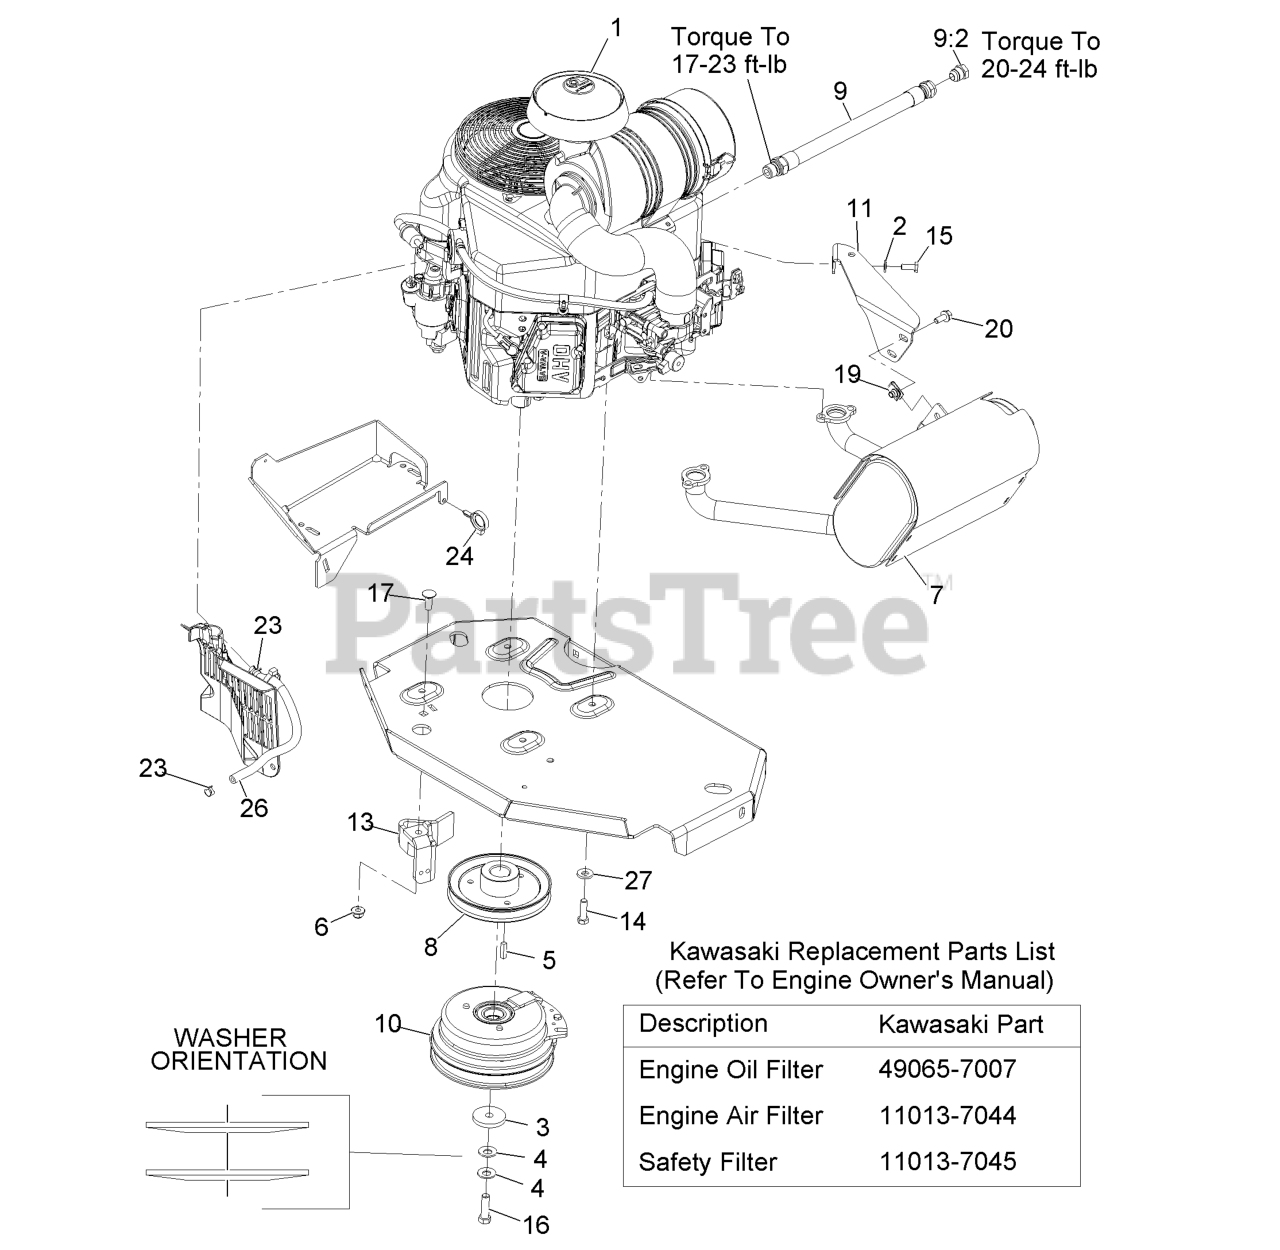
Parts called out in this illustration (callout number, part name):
2	WASHER-SPRING
3	WASHER-CLUTCH
4	WASHER-SPRING
6	NUT-HF, NI
7	MUFFLER
8	SHEAVE
10	CLUTCH KIT
11	BRACKET-MUFFLER
13	CLUTCH-ANCHOR
14	SCREW-HH
15	SCREW-HH
16	SCREW-HH 7/16-20 X 1 1/2 W/LOCTITE
17	SCREW-CARR
20	SCREW-HHF
23	CLAMP-HOSE
24	CLAMP-HOSE
26	HOSE-FUEL
27	WASHER-BELLEVILLE
